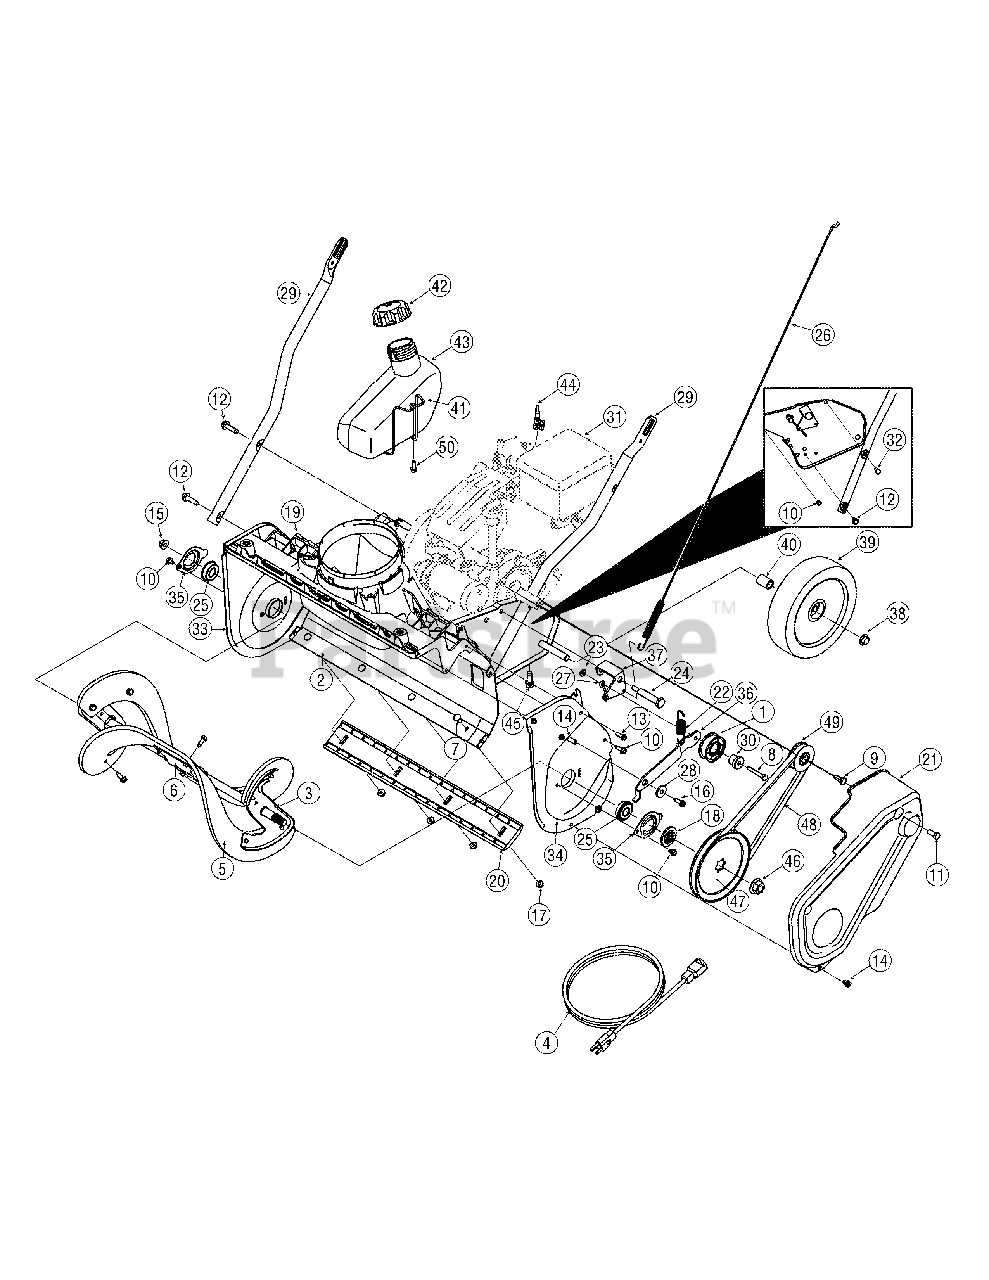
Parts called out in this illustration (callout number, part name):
1	Idler Pulley Assembly
2	Frame
3	Auger Axle Assembly
3	Auger Axle Assembly Complete
4	3-Prong Extension Cord
5	Auger Paddle Replacement Kit
5	Hex Washer Screw, 1/4-14 x .75
6	Center Auger Bracket
6	Hex Washer Screw 1/4-20 x.750
7	Carriage Screw, 1/4-20 x .62
8	Hex Washer Screw, 1/4-20 x 1.500
9	Hex Screw, 5/16-24 x .750
10	Hex Washer Screw, 1/4-20 x.625
11	Hex Flange Screw, 5/16-24 x .750
12	Hex Washer Screw, 5/16-18 x 1.250
13	Hex Washer Screw, 1/4-15 x .750
14	Hex Washer Screw, 1/4-20 x .500
15	Flange Lock Nut, 3/8-16
16	Hex Washer Screw, 5/16-18 x .750
17	Flange Lock Nut, 1/4-20
18	Pulley Hub
19	Chute Adapter
20	Shave Plate
21	Belt Cover
22	Extension Spring, .70 x 3.035
23	Push Nut, .25 x .50
24	Shoulder Bolt, 5/16-24 x .496 x 2.18
25	Ball Bearing
26	Clutch Cable
27	Drive Cable Wire Support
28	Shoulder Spacer
29	Lower Handle
30	Shoulder Spacer, .260 x .785 x .538
31	Replacement Engine
32	Hex Screw, 5/16-24 x 1.25
33	RH Auger Plate
34	LH Auger Plate
36	Idler Bracket
37	Cable Idler Bracket
38	Push Cap, 1/2
39	Wheel, 8 x 1.7
40	Sleeve Spacer, .525 x .78 x 1.00
41	Gas Tank Wire Support
42	Fuel Cap
43	Fuel Tank
44	Choke Extension Lever
45	Hex Washer Screw, 3/8-16 x 1.000
46	Flange Nut, 9/16-20
47	Pulley, 1/2 x 6.00
48	Belt, .500 x 35.06
49	Pulley Half, .625 x 2.25
